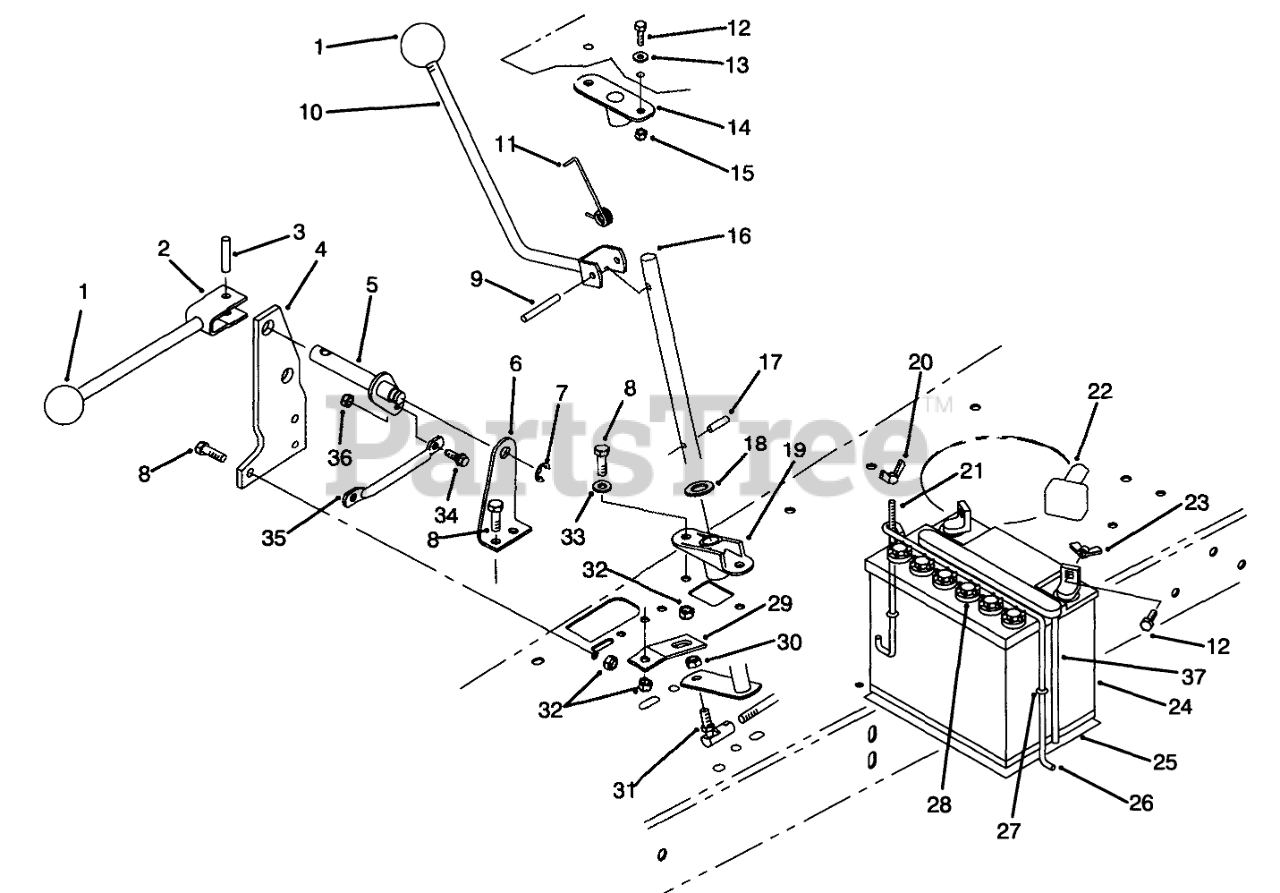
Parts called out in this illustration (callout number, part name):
2	Lever W.A.-Engage
3	PIN-ROLL
4	Pivot-Outer
5	PIVOT SHAFT WA
6	Bracket-Pivot, Inner
7	RING-RETAINING, EXTERNAL
8	SCREW-HH
9	PIN-ROLL
10	Lever W.A.-Shaft
11	SPRING-TORSION
12	SCREW-HH
13	WASHER-FLAT
14	SUPPORT-SHIFT SHAFT
15	NUT-LOCK, NI
16	SHAFT-SHIFT
17	PIN-SPRING
18	WASHER-THRUST
19	SUPPORT-LOWER SHIFTER
20	NUT-WING
21	POST-BATTERY
22	BOOT-TERMINAL
23	NUT-WING
24	Battery-12 Volt (Incl. Ref. #28 & 37)
25	PAD-SKID, ANTI
26	HOLDDOWN-BATTERY
27	O-RING
28	CAP-BATTERY
29	RETAINER-TRACTION SPRING
30	NUT-LOCK
31	JOINT-BALL
32	NUT-LOCK, NI
33	WASHER-PLAIN
34	SCREW-SHOULDER
35	LINK-BELLCRANK
36	NUT-HEX
37	TUBE-BATT DRAIN/80-2600
